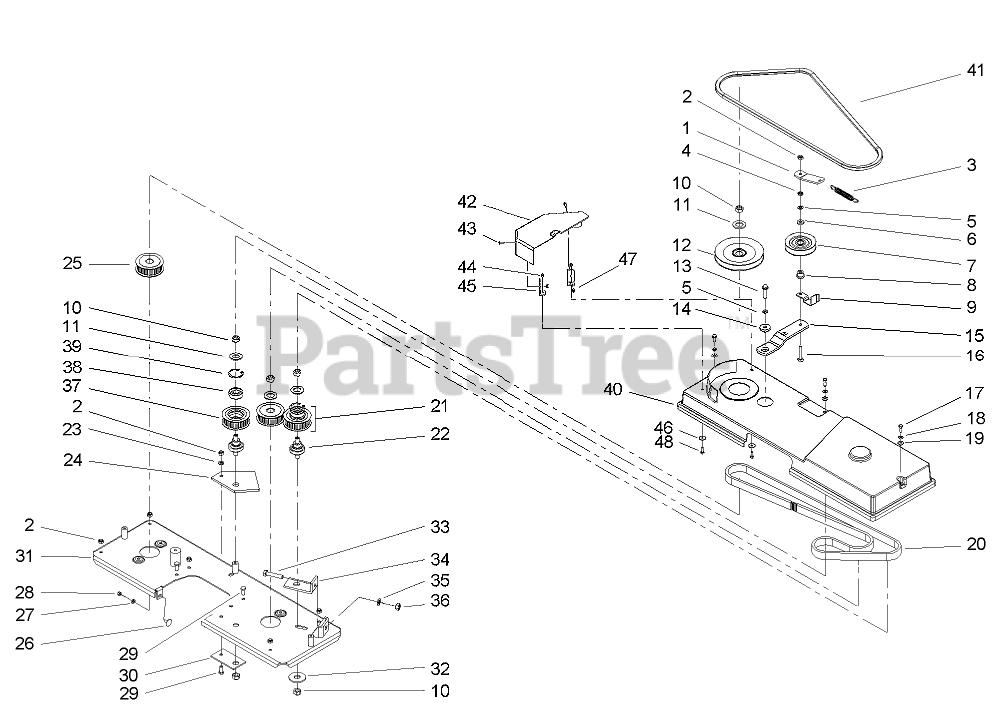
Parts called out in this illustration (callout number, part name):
1	LEVER-ENGAGEMENT
2	NUT
3	SPRING
4	NUT-JAM
5	WASHER-LOCK, SPRING
6	Washer-Flat
7	PULLEY-IDLER
8	BUSHING
9	RETAINER-BELT
10	NUT-LOCK, HEX NI
11	WASHER-FLAT
12	PULLEY-DRIVE
13	BOLT-HHF
14	SPACER-SHOULDER
15	ARM-IDLER
16	Screw-HH
17	SCREW-HH
18	Washer-Flat
19	WASHER-RUBBER
20	Belt-Cog
21	COG PULLEY ASM
22	PIN-PULLEY, Cog
23	WASHER-PLAIN
24	SUPPORT-PULLEY
25	PULLEY-COG, DRIVE
26	SCREW-CARR
27	WASHER-FLAT
28	NUT-LOCK
29	SCREW-HH
30	PLATE-ANCHOR
31	BLADE-DRIVE PLATE
32	WASHER
33	SCREW-HH
34	BRACKET-IDLER
35	WASHER-FLAT
36	NUT
37	Pulley-Cog
38	BEARING-BALL
39	RING-LOCKING
40	Belt-Cover
41	V-BELT
42	GUARD-BELT
43	SCREW-HH
44	NUT-LOCK
45	BRACKET
46	WASHER-FLAT
47	NUT-LOCK
